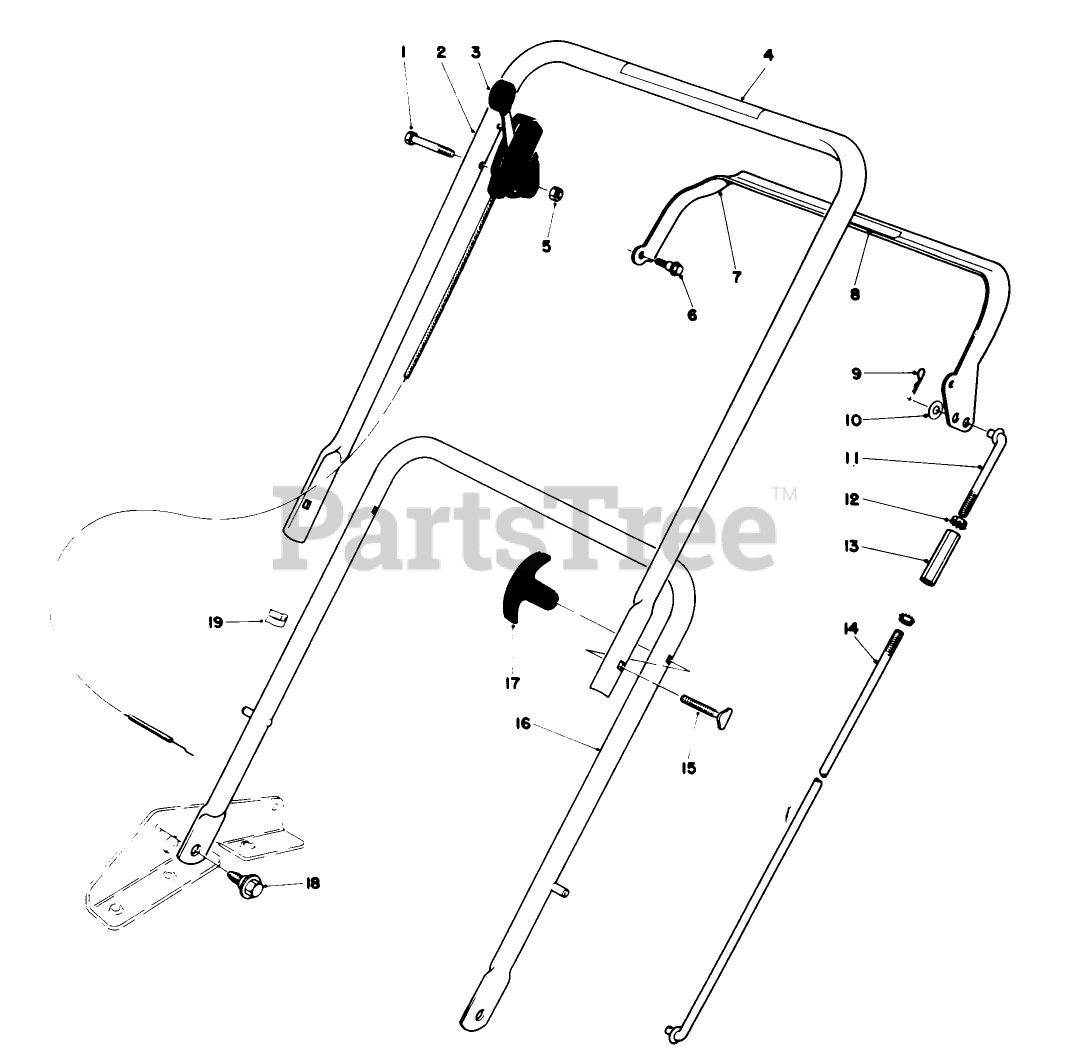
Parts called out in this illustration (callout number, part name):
1	SCREW-HH
4	Decal
10	WASHER-FLAT
12	NUT-KEPS
13	Sleeve-Control Rod
14	CONTROL ROD
18	SCREW-SHOULDER
